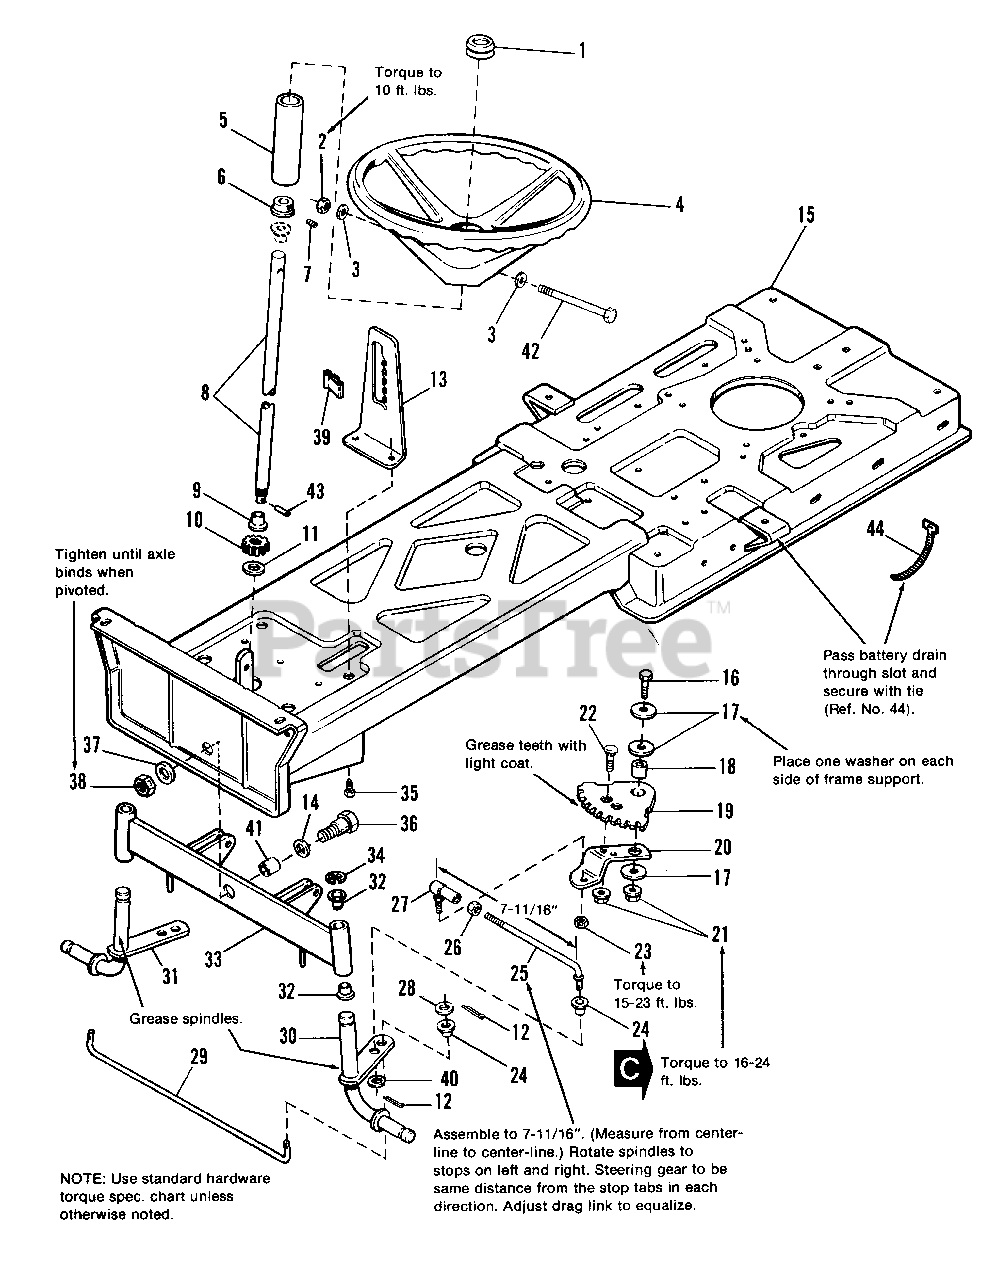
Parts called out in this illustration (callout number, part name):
1	CAP, Steering Wheel
2	LOCKNUT, Hex, Jam, 5/16-18
3	WASHER, 5/16
4	STEERING WHEEL
5	TUBE, Steering
6	COLLAR, Set
7	SETSCREW, Plated, 5/16-18 x 5/16
8	SHAFT, Steering
9	BUSHING, Nylon
10	PINION, Steering
11	WASHER, Plain, 1/2
12	PIN, Cotter, 1/8 x 1
14	WASHER, Plain
15	FRAME ASSEMBLY
16	CAPSCREW, Hex, 13/16 x 2
17	WASHER, Plain, 13/32 x 1-1/2
19	GEAR, Steering
20	ARM, Steering Gear
21	LOCKNUT, Hex, Flange, 3/8-16
22	BOLT, Carriage, 3/8-16 x 7/8
23	LOCKNUT, Hex, 3/8-24
26	NUT, Hex, Jam, 3/8-24
28	WASHER, Plain, 3/8
30	SPINDLE ASSY., L.H.
31	SPINDLE ASSY., R.H.
32	BUSHING, Nylon
33	AXLE ASSY.
34	E-RING, Retaining (3/4 dia. shaft)
35	SCREW, Taptite, 5/16-18 x 1/2
36	CAPSCREW, Hex Hd., 1/2-20 x 1-1/2
37	WASHER, Spring
38	LOCKNUT, Hex, Jam,1/2-20
40	WASHER, Plain, 3/8
42	BOLT, Hex, 5/16-18 x 3-1/2
43	PIN, Spring
44	TIE, Self-Locking
